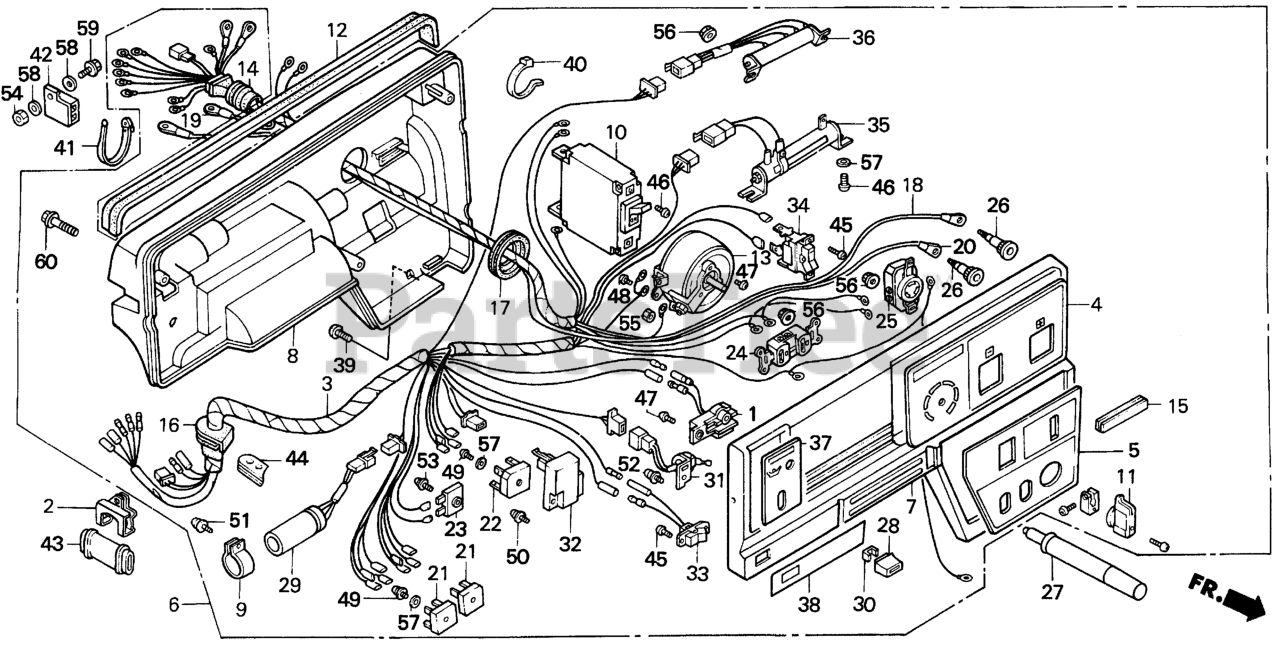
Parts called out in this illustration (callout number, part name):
1	ALERT UNIT, OIL (NOT AVAILABLE)
2	CLIP, WIRE
3	WIRE HARNESS ASSY.
4	MARK, CURRENT CONTROL
5	MARK, A.C. OUT
6	BOX ASSY., CONTROL *R8* (BRIGHT RED)
7	PANEL, CONTROL *R8*
8	CASE, CONTROL *R8* (BRIGHT RED)
9	HOLDER, CONDENSER
10	BREAKER, CIRCUIT (12A)
11	KNOB, ADJUSTING
12	RUBBER, CONTROL
13	RESISTOR, VARIABLE
14	GROMMET, A.C. WIRE
15	GROMMET, COVER
16	GROMMET, SWITCH WIRE
17	GROMMET, MAIN WIRE
18	WIRE A, WELDER TERMINAL
19	WIRE B, WELDER TERMINAL
20	WIRE C, WELDER TERMINAL
21	STACK, DIODE
23	STACK, DIODE
24	RECEPTACLE (20A/125V) (MATSUSHITA)
24	RECEPTACLE (20A/125V)
25	RECEPTACLE (30A/125V)
25	RECEPTACLE (3-PRONG) (30A/125V)
26	RECEPTACLE, PANEL
27	CONNECTOR, MALE
28	KNOB, PETCOCK LEVER
29	CAPACITOR ASSY.
30	BUSH, CONTROL KNOB
31	SWITCH ASSY., ENGINE STOP
32	THROTTLE UNIT ASSY., AUTO
33	SWITCH, AUTO THROTTLE
34	SWITCH ASSY.
35	RESISTOR, ADJUSTABLE
37	MARK, ENGINE SWITCH
38	MARK, AUTO-THROTTLE (EB-A)
39	SCREW, GLOVE BOX
40	TIE, CABLE (NATURAL 225X5.0)
41	TIE, CABLE
42	CLIP, WIRE HARNESS
43	TUBE, CORD
44	GROMMET, TUBE
45	SCREW, PAN (3X6)
46	SCREW, PAN (4X6)
47	SCREW, PAN (4X8)
48	SCREW, PAN (4X10)
49	SCREW-WASHER (4X20)
50	SCREW-WASHER (5X12)
51	SCREW-WASHER (4X10)
52	SCREW-WASHER (5X12)
52	SCREW-WASHER (5X14)
53	SCREW-WASHER (5X20)
54	NUT, HEX. (6MM)
55	NUT, HEX. (4MM)
56	NUT, FLANGE (4MM)
57	WASHER, PLAIN (4MM)
58	WASHER, PLAIN (6MM)
59	BOLT, FLANGE (6X32)
60	BOLT, FLANGE (6X40)
